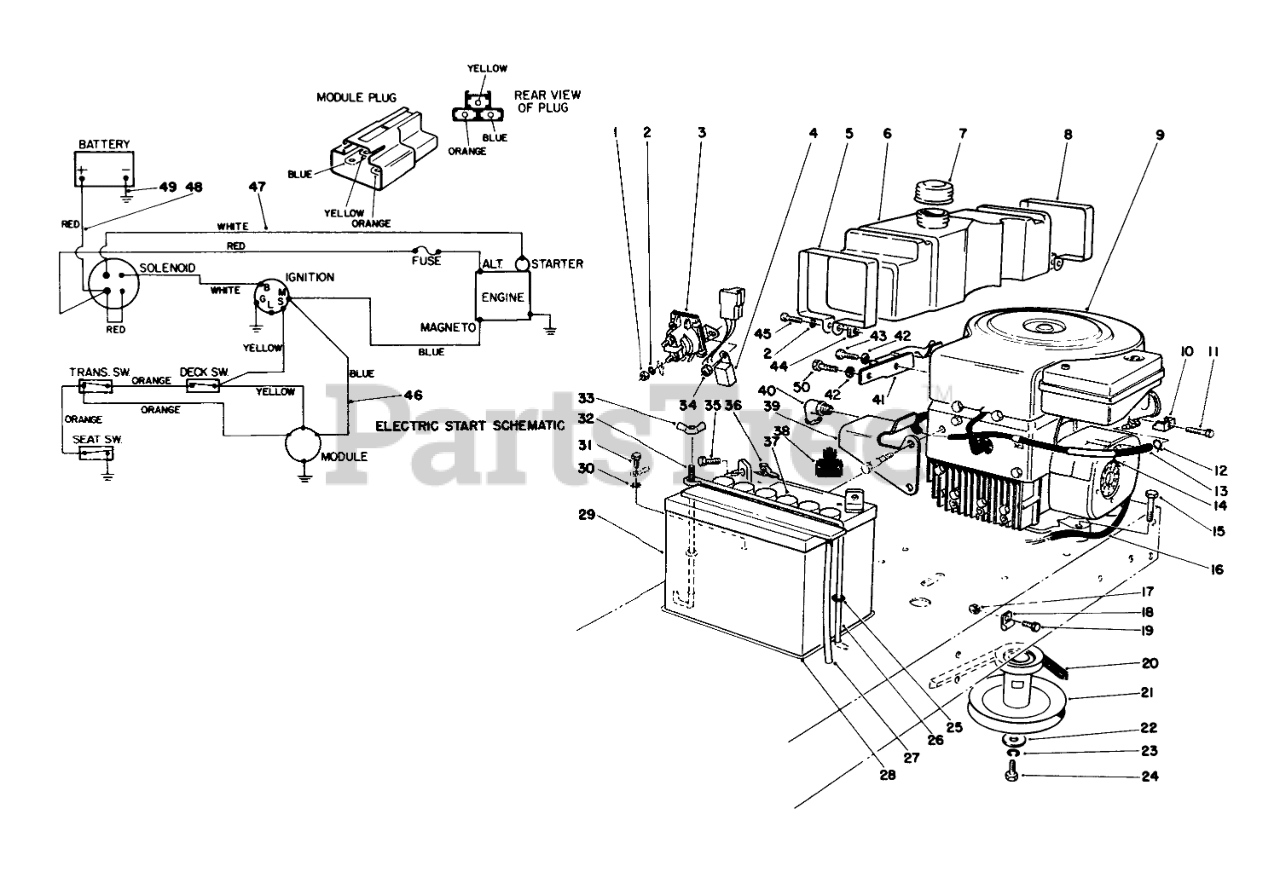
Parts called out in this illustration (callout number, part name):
1	NUT-JAM
2	WASHER-LOCK
3	SOLENOID
4	Module Interlock
5	Retainer-Front
6	TANK-5 QT GAS
7	GAS CAP ASM
8	Retainer-Rear
9	Engine-11 H.P.
10	CLAMP-CASING
11	SCREW W ENGINE
12	CLAMP-HOSE
13	FUEL HOSE
14	SUPPORT-FUEL LINE
15	SCREW-HH
16	HEAT SHRINK TUBING
17	NUT-LOCK, NI
18	CLAMP
19	SCREW-HH
20	V-BELT, TRACTION
21	PULLEY
22	WASHER-FLAT
23	WASHER-LOCK
24	SCREW-HH
25	O-RING
26	HOLDDOWN-BATTERY
27	TUBE-BATT DRAIN/80-2600
28	PAD-SKID, ANTI
29	Battery
30	WASHER-LOCK, INTERNAL
31	SCREW-HHF
32	POST-BATTERY
33	NUT-WING
34	NUT-LOCK, CONE
35	SCREW-HH
36	NUT-WING
37	CAP-BATTERY
38	BOOT-TERMINAL
39	BRACKET B
40	ELBOW-STREET, 90 DEG
41	REAR TANK MTG BRKT B
42	WASHER-PLAIN
43	SCREW-HH
44	NUT-SQUARE
45	SCREW-HSH
46	Wire Harness
47	STARTER WIRE HARNESS
48	WIRE ASM
49	WIRE ASM(BATT/GRD.
50	SCREW-HH
